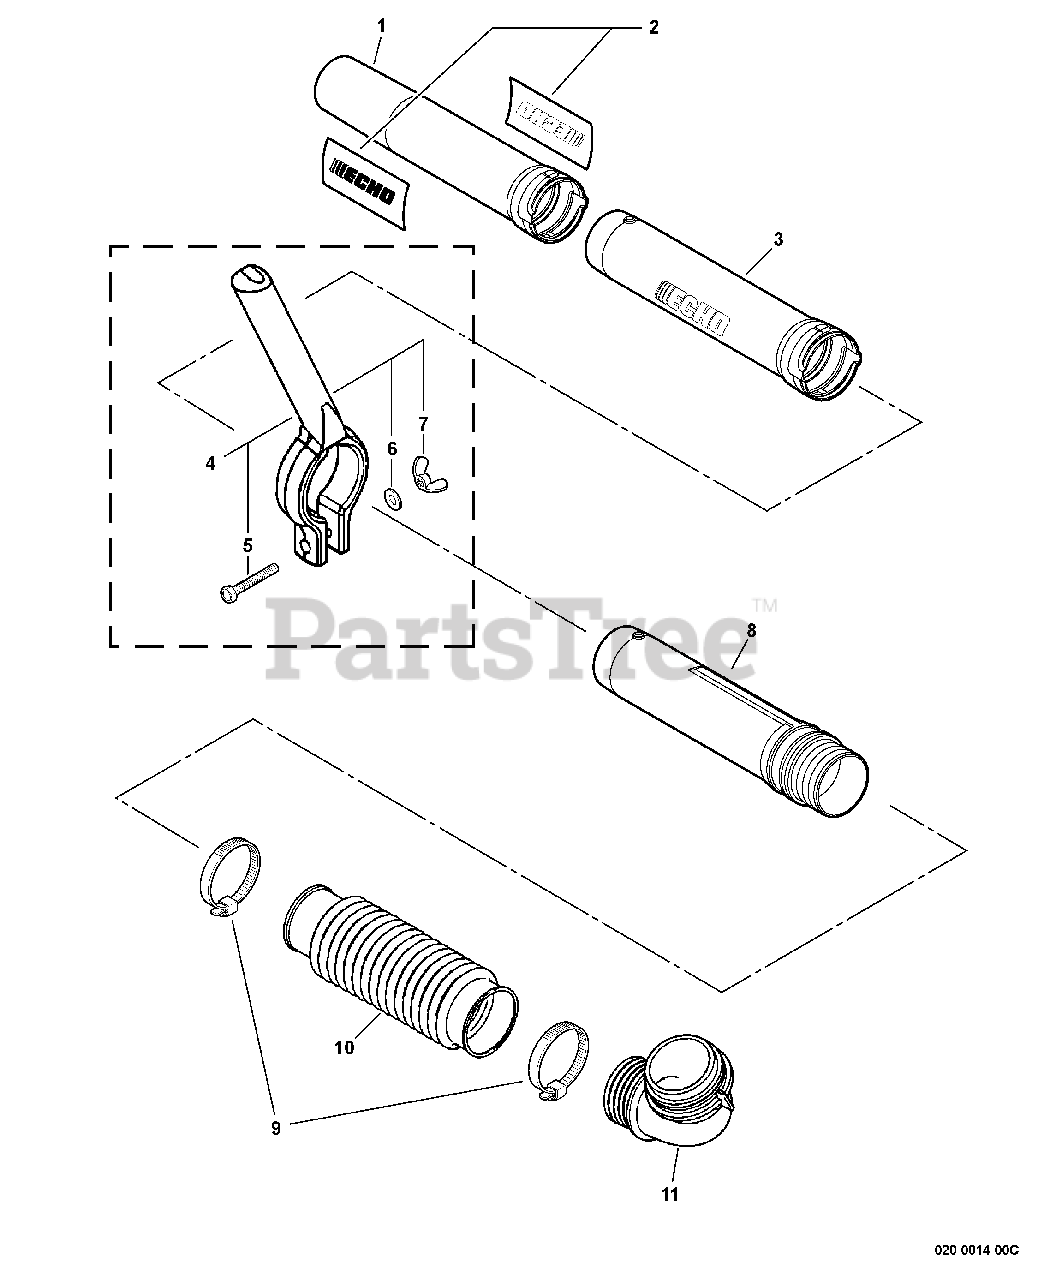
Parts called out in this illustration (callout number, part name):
1	TUBE, BLOWER - STRAIGHT
2	LABEL - ECHO
3	TUBE, BLOWER - STRAIGHT
4	TUBE MOUNT HANDLE
5	BOLT - 6X45
6	WASHER - 6
7	WINGNUT - 6
8	TUBE, BLOWER - SWIVEL
9	CLAMP, HOSE
10	TUBE, BLOWER - FLEXIBLE
11	TUBE, BLOWER - ELBOW
